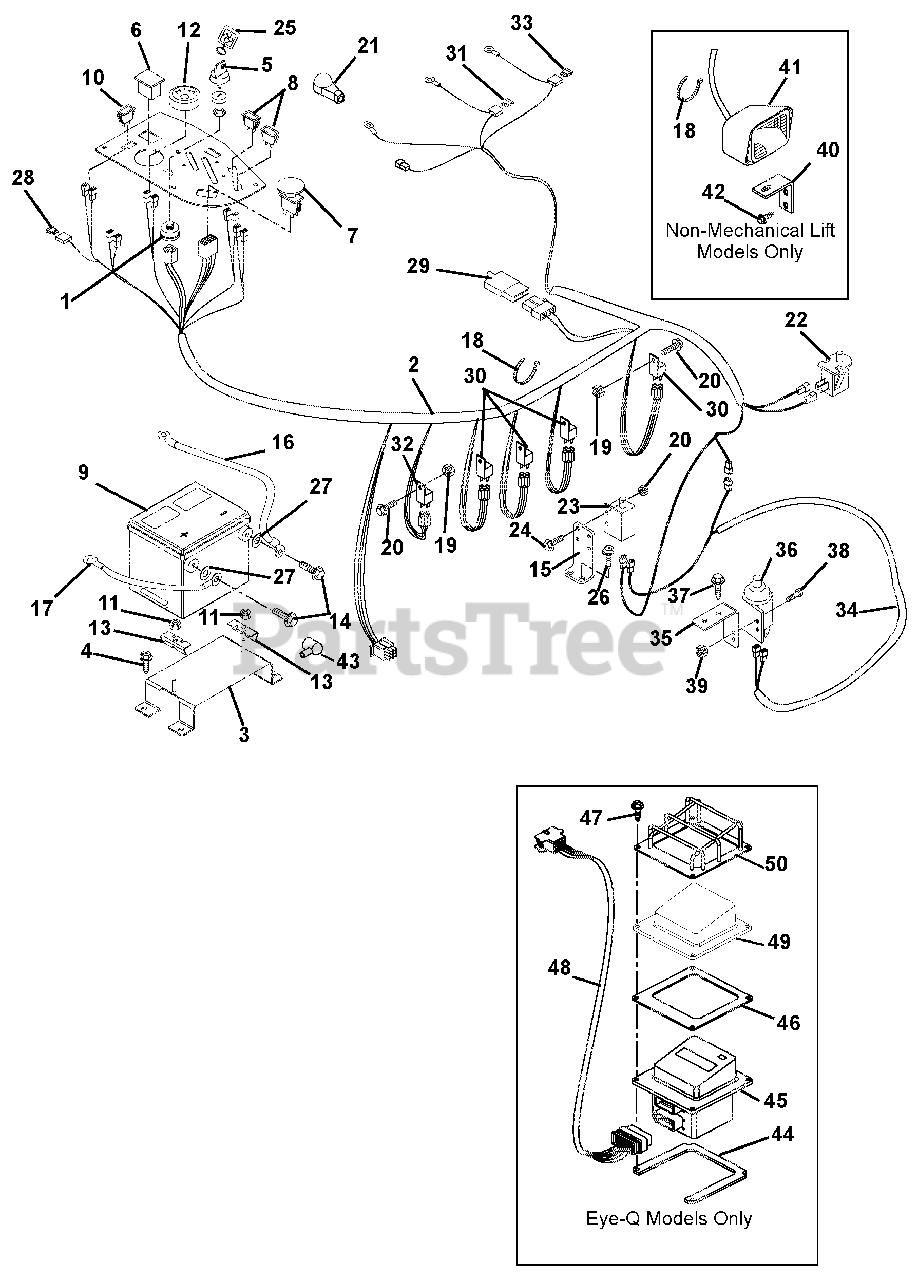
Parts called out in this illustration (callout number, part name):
1	SWITCH, IGNITION (DIESEL)
2	HARNESS, HORZ. L/C(DIESEL)
3	WMT, BATTERY SUPPORT
4	@SCR-TAP .38-16X.75 HWH TR YWZ
5	KEY, W/ SHIELD
6	PLUG, HOUR METER
7	SWITCH, CLUTCH
8	LIGHT,INDICATOR
9	BATTERY, GROUP 70 450 CCA 35 A
10	SWITCH, 2 POLE/ROCKER
11	@NUT-LK-TOP-FLG .31-18 YWZC
12	GAUGE, TEMPERATURE
13	BRKT, BATTERY HOLD-DOWN
14	BATT TERMINAL SCREW
15	MOUNT, SAFETY SWITCH
16	CABLE, POS BATT 4 GA X 45
17	CABLE, NEGATIVE BATTERY 49.00
18	CABLE TIE LG 5-1/2
19	@SCR-MCH 10-24X.75 HWH YWZC
20	@NUT-LK-NYL 10-24 W/INSRT YWZC
21	BOOT, EYELET TERMINAL
22	SWITCH- SNAP MTG N.O.
23	SWITCH- SINGLE POLE N.O.
24	@SCR-MCH 10-24X.75 HWH YWZC
25	KEY CHAIN
26	@SCR-TAP .25-20X.50 HWH TR YWZ
27	@WSHR-FL-STL.38X.875X.083 YWZC
28	FUSE, 15 AMP.
29	DIODE, CONNECTOR SHELL
30	RELAY
31	FUSE, 30 AMP.
32	Pre-Heat Timer
33	FUSE, 50 AMP (MAXI FUSE)
34	HARNESS, WIRE ADAPTER CE
35	MOUNT - SWITCH
36	SWITCH-SINGLE POLE N.O.W/COVER
37	@SCR-TAP .31-18X.50 HWH TR YWZ
38	@SCR-MCH 10-24X.75 HWH YWZC
39	@NUT-LK-NYL 10-24 W/INSRT YWZC
40	BRACKET, HEADLIGHT MTG
41	HEADLIGHT
42	@SCR-TAP .38-16X.50 HWH TR YWZ
43	BOOT, EYELET TERMINAL
44	SPACER, ENCLOSURE MTG. (BTM)
45	ASSY, EYE-Q
46	GASKET-EYE Q
47	SCR-MCH 10-24X1.0 SL PAN BLACK
48	HARNESS, EYE-Q
49	GUARD, ELEMENT
50	GUARD, VINYL EYE-Q
